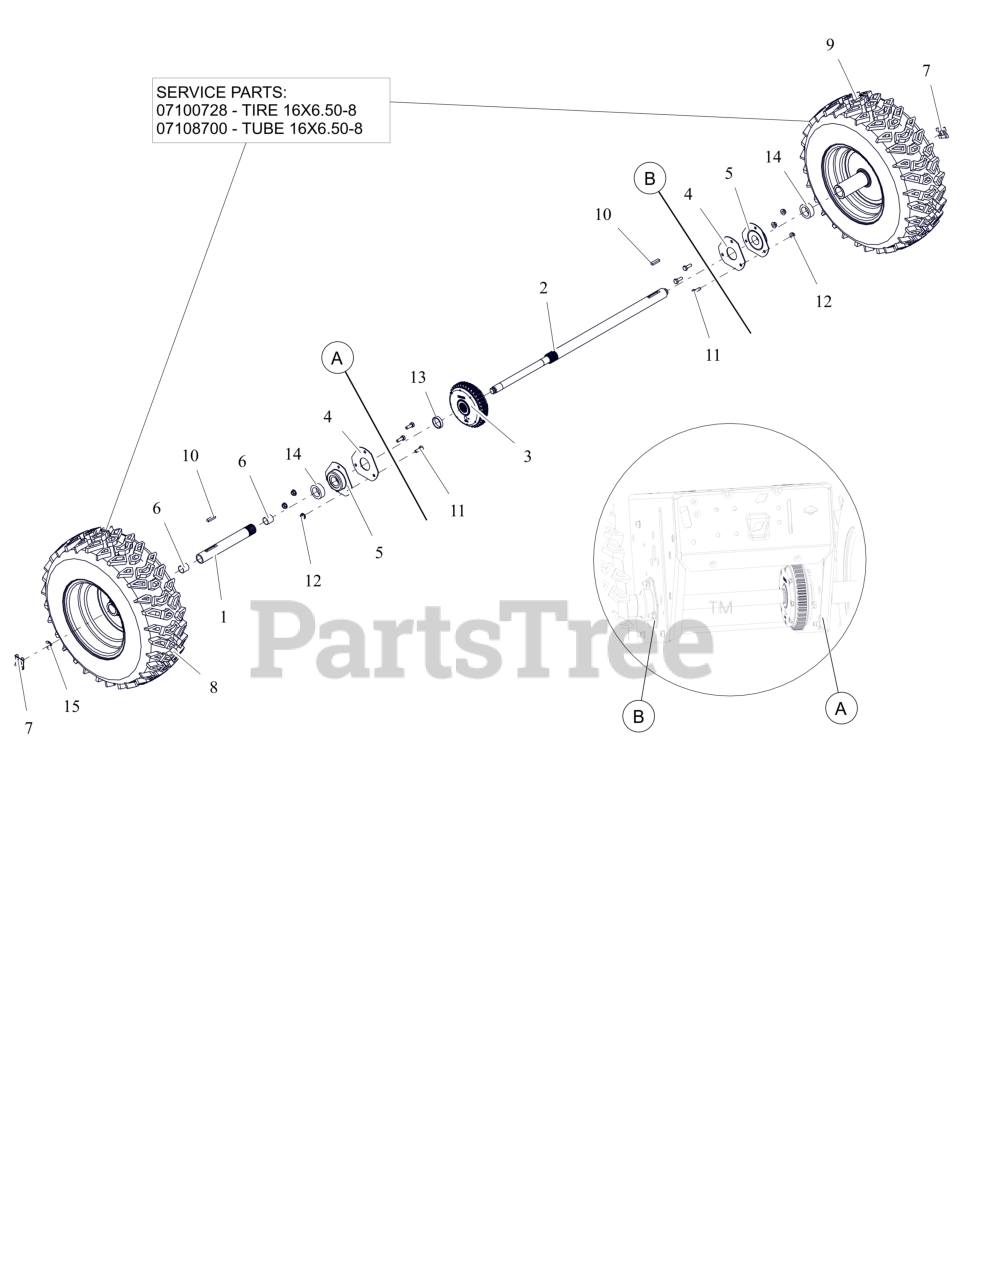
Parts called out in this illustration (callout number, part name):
1	AXLE, SHORT-AUTO W/BUSHINGS
2	AXLE, LONG-PRO AUTO DIFF
3	DIFFERENTIAL, AUTOMATIC
4	PLATE, BEARING SPACER
5	BRG-FLG 1.003/1.000 3 BOLT
6	BSHG-SLV .706X.764X.75 BRZ
7	CLIP, SNAP .625 DIA
8	TIRE/WHEEL RH 16X6.5-8 DIFF T2
8	SNOW TIRE, 16/6.50-8 K478 DIRECTIONAL
8	TIRE TUBE 16X6.50/7.50-8 4 PLY TR13 STRIGHT VALVE
9	TIRE/WHEEL LH 16X6.5-8 DIFF T2
9	SNOW TIRE, 16/6.50-8 K478 DIRECTIONAL
9	TIRE TUBE 16X6.50/7.50-8 4 PLY TR13 STRIGHT VALVE
10	KEY-RECT .25X.188X1.00
11	BLT, HEX .25-20X.75 G5 ZCC
12	NUT-LK-CTR-FLG .25-20 ZC120
13	BSHG, SLV 1.062X1.228X.268
14	SPACER, PRO AXLE BEARING
15	RG-RTNG-EXT .625X.042
